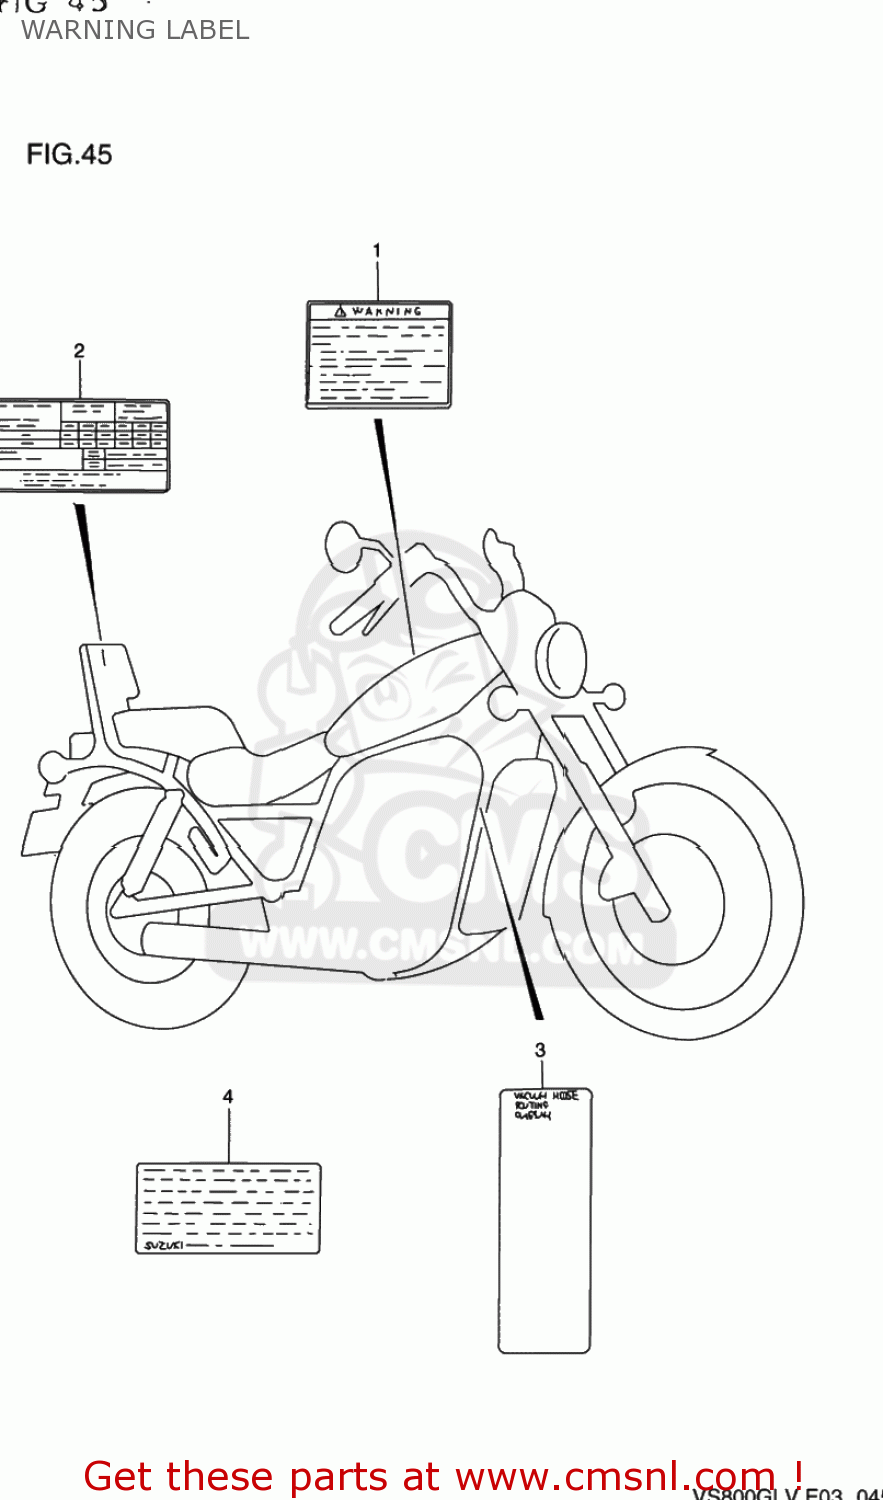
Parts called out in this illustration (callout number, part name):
1	LABEL (WARNING SAFETY),E
2	LABEL (TIRE AIR PRESSURE)
3	LABEL,VACUUM HOSE ROUTING
4	LABEL (MANUAL NOTICE)
5	MANUAL, OWNER'S
